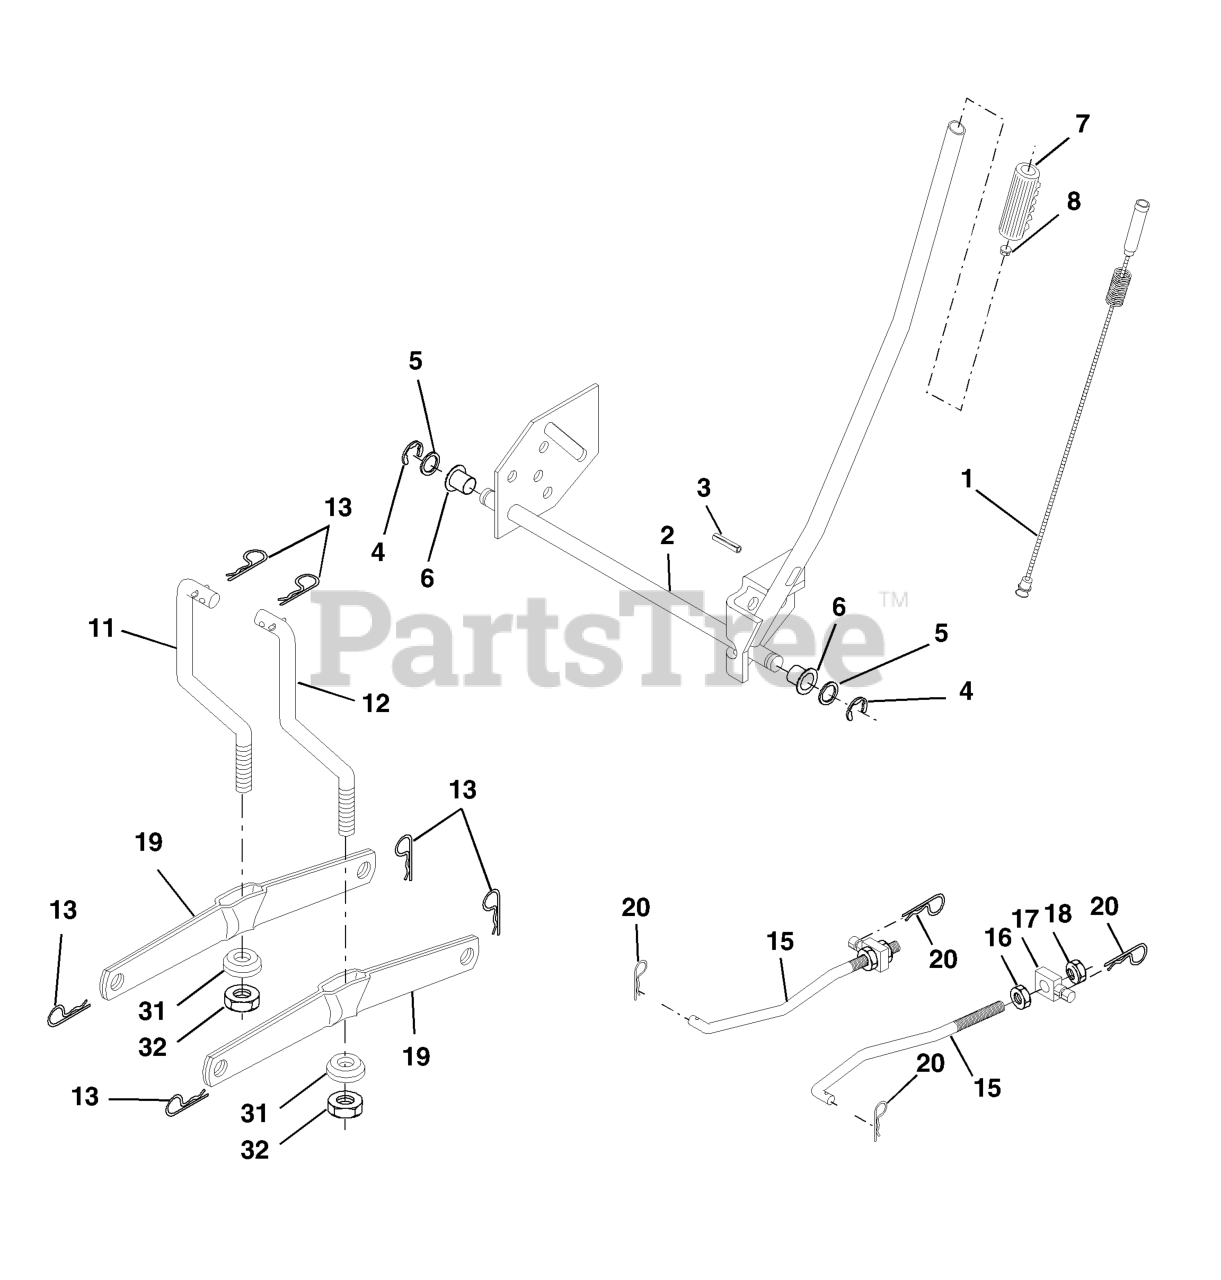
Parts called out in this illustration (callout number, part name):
1	WIRE ASM INNER W/ PLUNGER LT
2	SHAFT ASM R HANDLE
3	PIN GROOVE.
4	RETAINING RING LT
6	BEARING.NYLON
8	PLUNGER BUT KIT
11	LINK LIFT LH
12	LINK LIFT RH
13	RETAINER-SPRNG RB
15	LINK.SUSPENSION.FRONT
16	NUT.HEX.JAM.1/2-13
18	NUT.LK.W/WSH.1/2.
19	ARM.REAR.SUSPENSION
20	SPRING RETAINER
31	BEARING.PIVOT.LIFT
32	NUT CROWNLOCK 3/8-24
